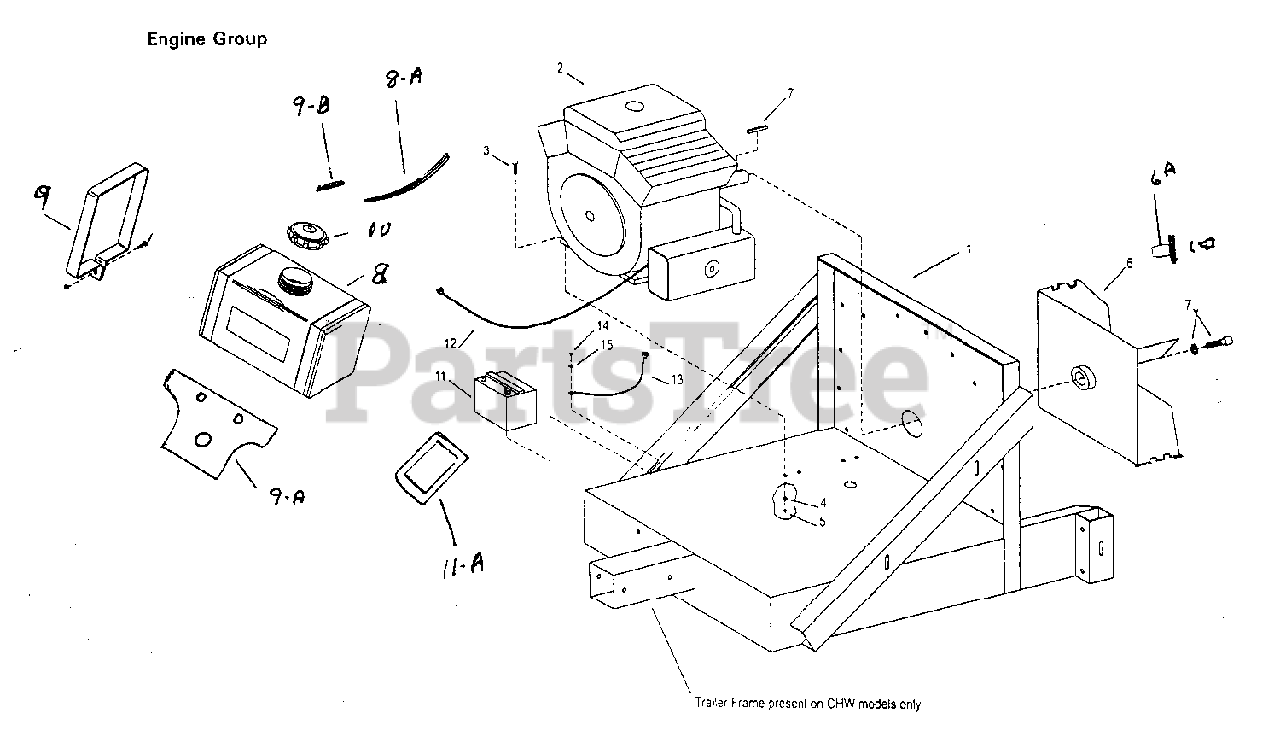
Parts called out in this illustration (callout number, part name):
1	Engine Base SKID Mounts
1	Engine Base & Trailer Frame CHW
2	* 20HP Kohler Command Engine
2	* 25HP Kohler Command Engine
3	3/8 x 2" Hex Bolt (Motor Mount Bolt)
3	3/8 x 1-3/4" Hex Bolt (Motor Mount Bolt)
4	3/8 Lock Washer
5	3/8 Hex Nut
6	Impeller, 20"
6A	Impeller Hub
7	5/8-18 x 2" Impeller Bolt & Key Group
8	Fuel Tank
8A	Hose, Rubber Fuel 1/4" x 10" Length
9	Fuel Tank Strap
9A	Gas Tank Mount
9B	Inline Fuel Shutoff Valve
11A	Battery Box
12	Battery Cable - 32SS (Positive)
13	Battery Cable - 16SS (Ground)
14	3/8 Hex Nut (secures ground cable to engine base)
15	3/8 Lock Washer
